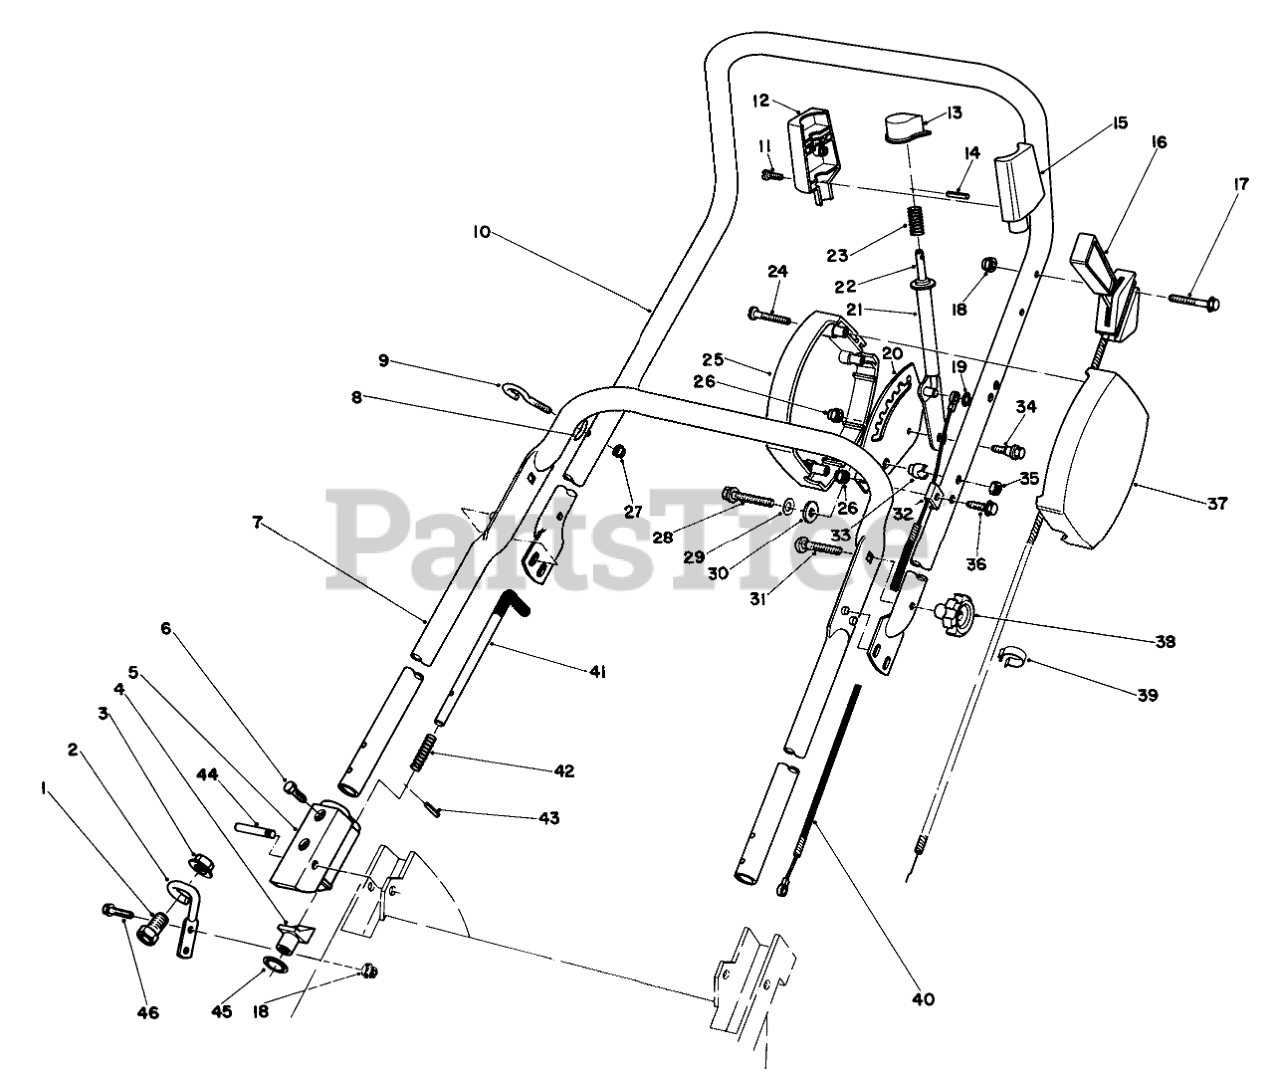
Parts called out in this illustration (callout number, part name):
1	Sleeve-Rope
2	Guide-Rope
3	NUT-LOCK
4	Bushing-Insulated
5	Block-Handle Mounting
6	SCREW-SHWH, THREAD FORMING
7	Lower Handle
8	Washer-Curved
9	Eyebolt
10	UPPER HANDLE
11	Screw-Pan Head
12	Grip-Right Hand
13	Button-Height of Cut
14	PIN-SPRING
15	Grip-Left Hand
16	Control-Throttle
17	Screw-Hex Washer Head
18	NUT-LOCK
19	PUSH NUT
20	Bracket-Detent
21	Handle-Height fo Cut
22	Rod-Detent
23	COMPRESSION SPRING O
24	8 X1.25 SELF TAP SCRW
25	Cover-Control R.H.
26	M6 X 1 LOCKNUT
27	NUT-CAP
28	Capscrew
29	WASHER-PLAIN
30	Washer-Insulator
31	SCREW-CARR
32	Clamp-Cable
33	Isolator-Control
34	Shoulder Screw
35	NUT-LOCK
36	Screw-Cap Hex. Hd.
37	Cover-Control L.H.
40	HOC UPPER CABLE
41	Rod-Latch
42	COMPRESSION SPRING
43	PIN-ROLL, SLOTTED
44	Pin-Handle Mounting
45	SPEED NUT
46	Screw-Hex Head
